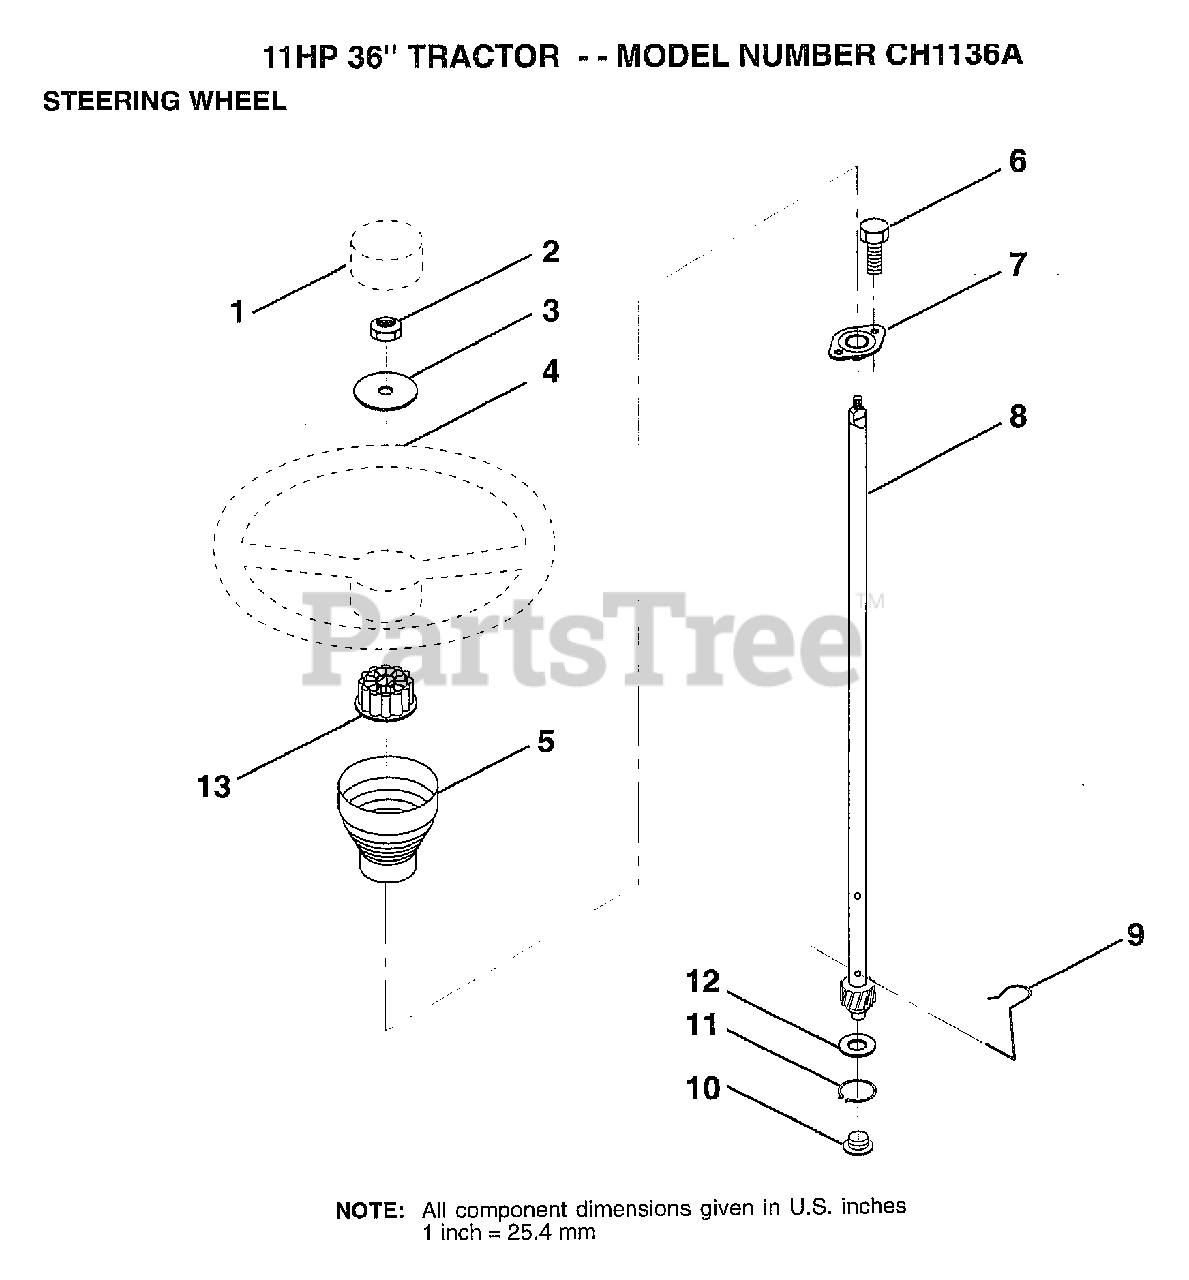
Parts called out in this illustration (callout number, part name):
1	ST WHL INSERT CAP
2	GRIPCO NUT
3	WASHER T
5	SLEEVE STEERING
9	STEERING CLIP
10	BUSHING STEER LWR
11	RING
12	WASHER LT
13	ADAPTER-WHEEL LT
